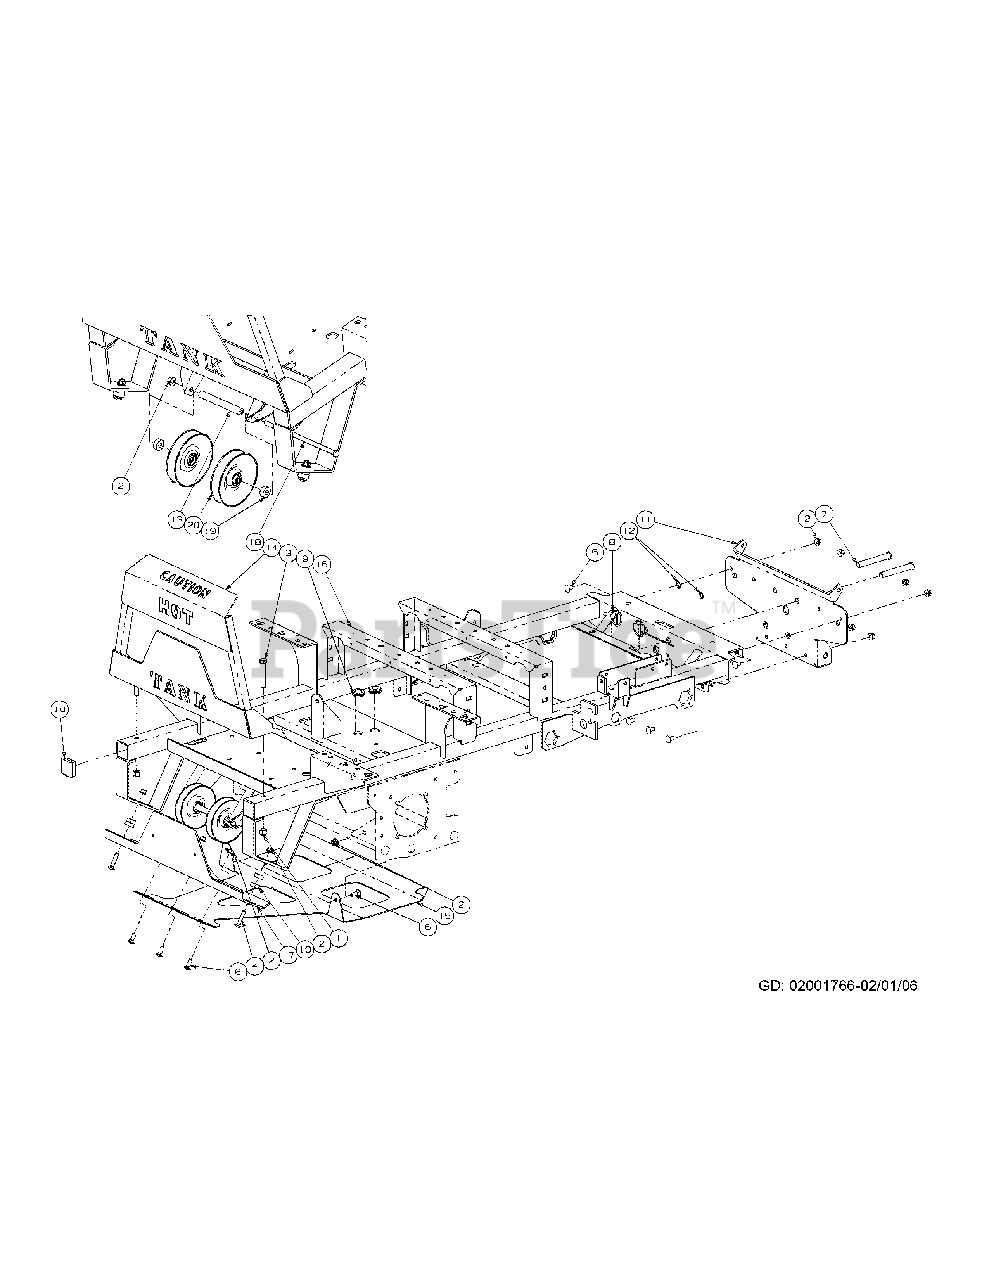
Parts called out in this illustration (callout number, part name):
1	Lock Nut, Nylon Insert, 1/2-13
2	Hex Nut, 3/8-16 Flange Lock
3	Hex Head Cap Screw, 1/2-13 x 3.00
4	Carraige Bolt, 3/8-16 x 1.75
5	Carriage Bolt, 3/8-16 x .75 Long
6	Carriage Bolt, 3/8-16 x 1.00
7	Clevis Pin, .625 Dia x 4.375 Long
8	Linch Pin, 3/16 Dia.
9	Grommet .75 ID
10	Plug, Square Tube
11	Bracket Assembly, Frame, Front
12	Push Retainer, 3/8
13	Spacer, .385 ID x .625 OD x 4.89
14	Muffler Guard Assembly
15	Skid Plate
16	Frame Assembly
17	Guard Bracket
18	Hex Head Cap Screw, 3/8-16 x 8.50
19	Spacer, .406 ID x 1.00 OD x .380
20	Idler Pulley, 5.06 Dia.
